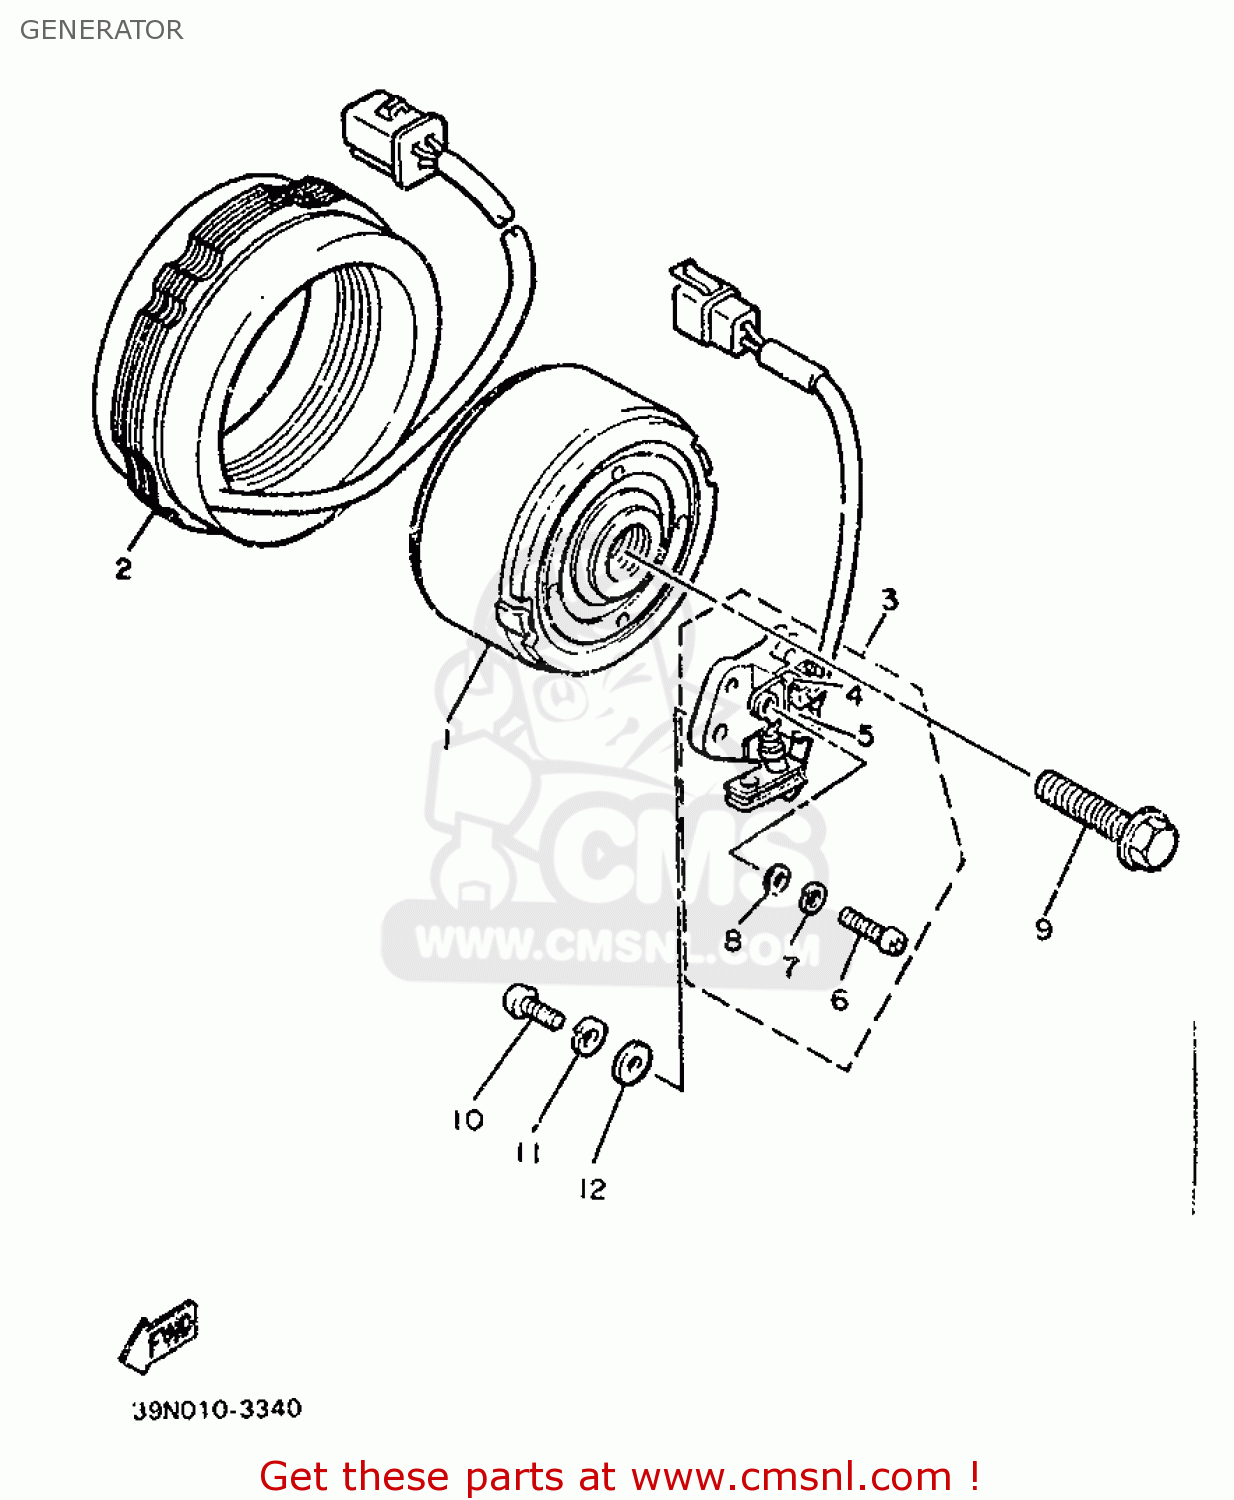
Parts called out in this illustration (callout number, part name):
01	ROTOR ASSY
02	STATOR ASSY
03	BRUSH HOLDER ASSY
04	BRUSH 1
05	BRUSH 2
06	SCREW, PANHEAD (4U5)
07	WASHER,SPRING
08	WASHER, PLATE (525)
09	BOLT, WASHER BASED (4H7)
10	SCREW, PAN HEAD (J10)
11	WASHER,SPRING
12	WASHER, PLAIN (646)
